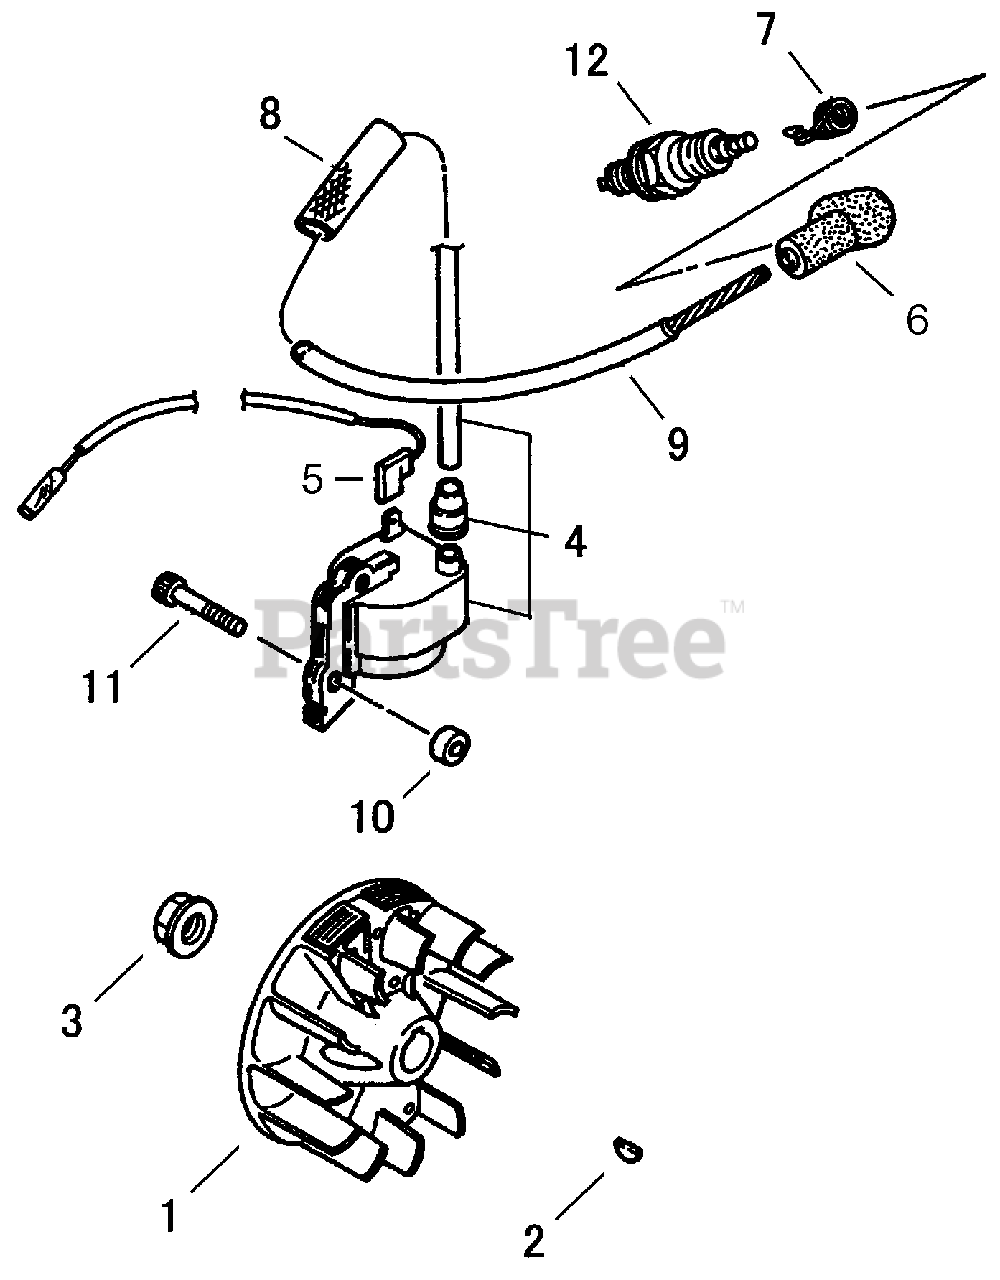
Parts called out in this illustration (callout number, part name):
1	FLYWHEEL
2	KEY, WOODRUFF 3×10
3	NUT M8
4	COIL ASSY, IGNITION
5	LEAD - IGNITION
6	CAP, SPARK PLUG
7	TERMINAL, SPARK PLUG
8	TUBE, IGNITION COIL
9	TUBE, INSULATOR
10	INSULATOR 4.2×11×6
11	BOLT M4×26
12	SPARK PLUG - BMR6A
